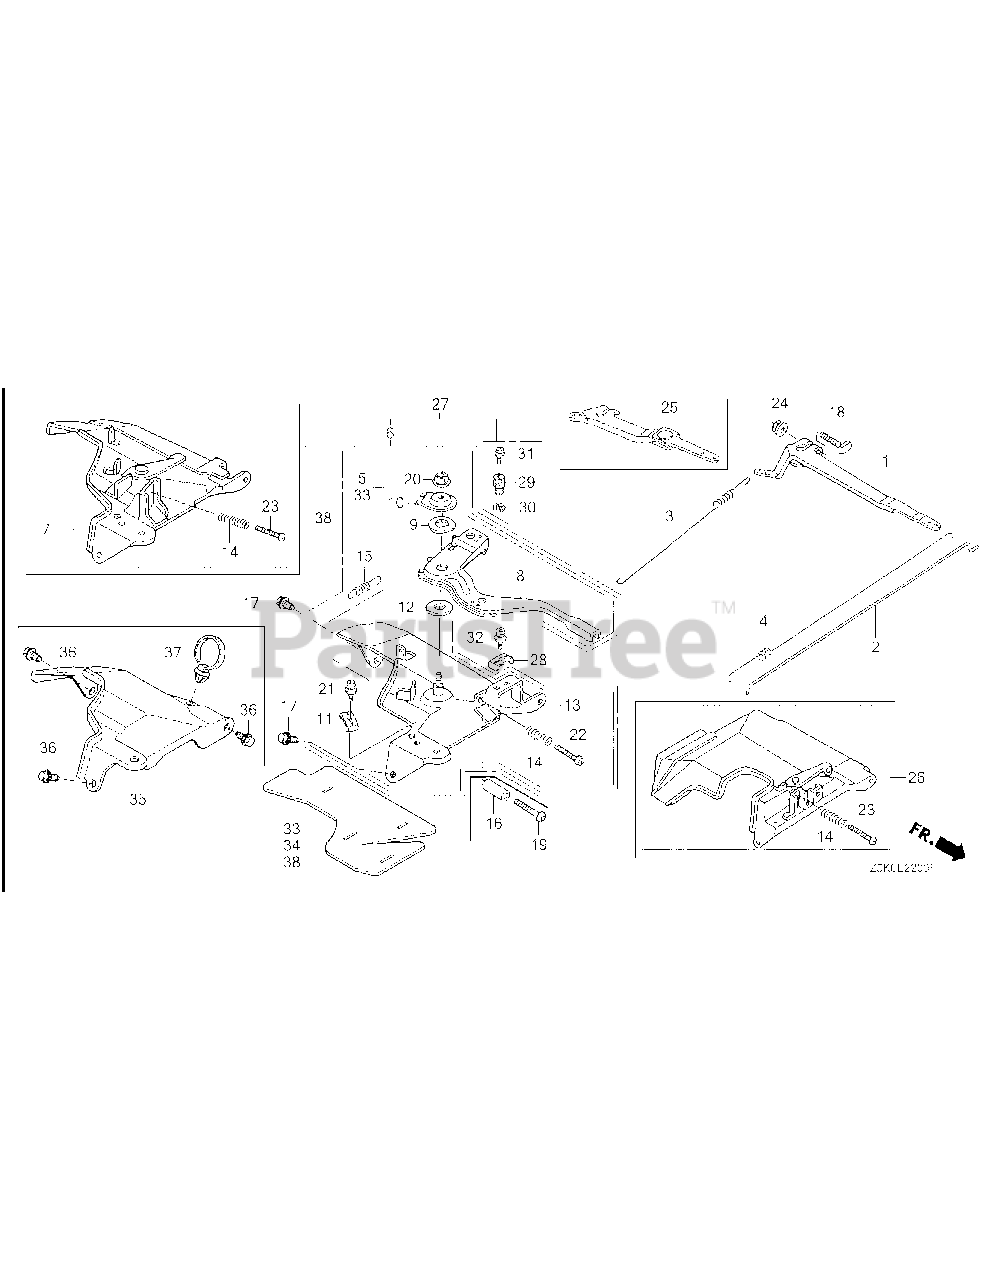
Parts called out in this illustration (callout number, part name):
1	Arm, Governor
2	Rod, Governor
3	Spring, Governor(L=145.0Mm)(Wire Diameter 1.0Mm)
4	Spring, Throttle Return
5	Control Assy.
6	Control Assy.
7	Control Assy.
8	Lever, Control
9	Spring, Lever
10	Washer, Control Lever
11	Holder, Cable
12	Spacer, Control Lever
13	Base Comp., Control
14	Spring, Control Adjusting
15	Spring, Cable Return
16	Collar, Stopper
17	Bolt, Flange, 6X12(Ct200)
18	Bolt, Governor Arm
19	Screw, Recessed, 5X25
20	Nut, Self-Lock, 6Mm
21	Screw, Pan, 5X16
22	Screw, Pan, 5X28
23	Screw, Pan, 5X35
24	Nut, Flange, 6Mm
25	Arm Comp., Governor
26	Control Assy.
27	Control Assy.(Remote)
28	Holder, Cable
29	Holder, Wire
30	Circlip, 5Mm
31	Screw, Pan, 4X6
32	Screw, Pan, 5X16
33	Control Assy.
34	Insurator, Control Base
35	Shroud Comp., Upper
36	Bolt, Flange, 6X12(Ct200)
37	Clip, Harness Band(Black)(145Mm)
38	Control Assy.(Remote)
